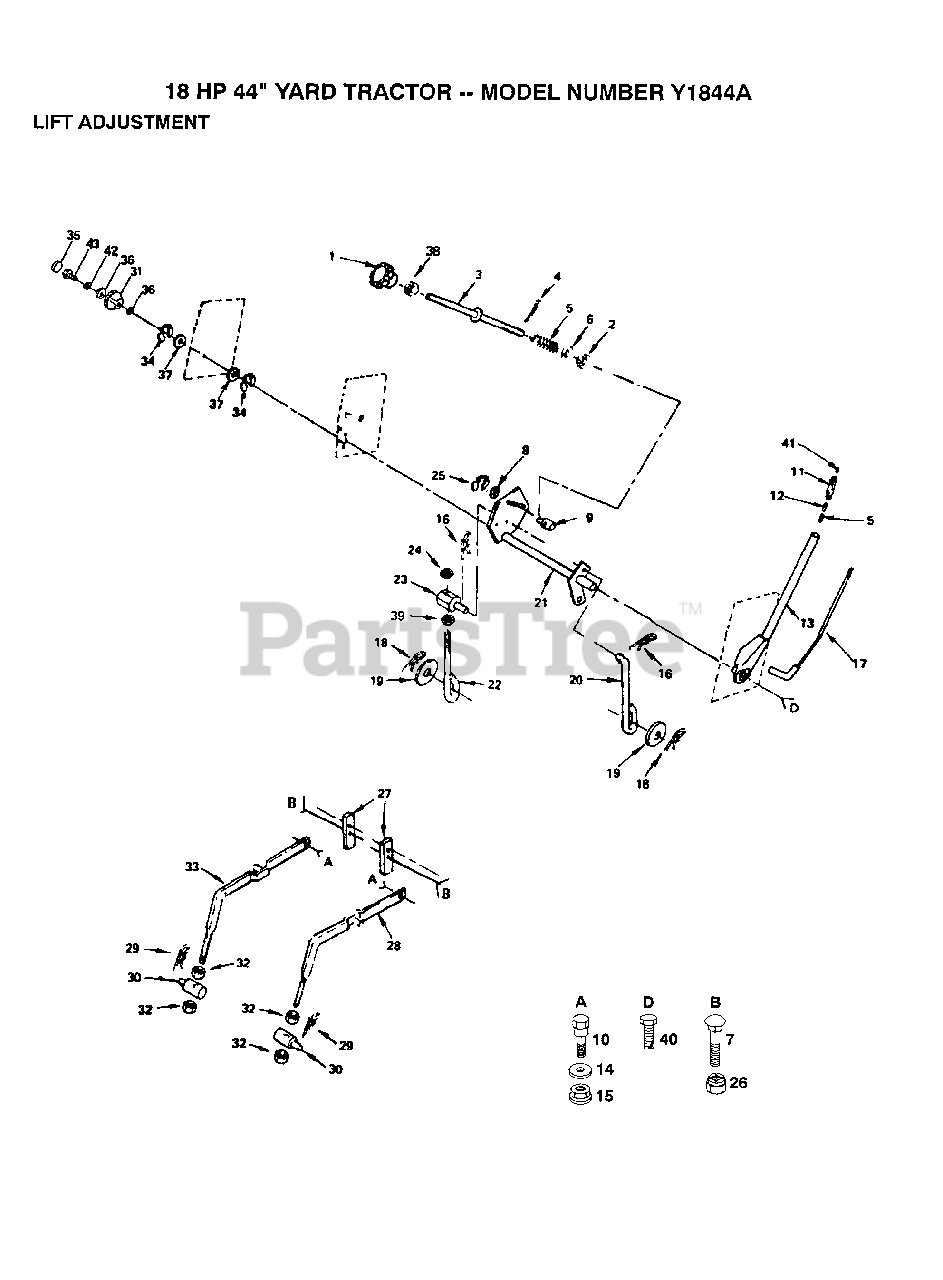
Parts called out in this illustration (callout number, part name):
2	NUT T
3	ROD LIFT LT
5	SPRING T
6	WASHER
8	WASHER
9	TRUNION LT
10	"BOLT, SHOULDER LT"
11	GRIP
14	WASHER T
15	NUT SPECIAL T
17	LEVER ROD LT
18	SPRING.RETAINER
20	LIFT LINK LT
22	PIVOT PIN T
25	KLIP RING
27	UPSTOP
28	RH SUSP ARM ASM
29	SPRING H
31	HEIGHT INDICATOR
32	NUT
33	LH SUSP ARM ASM
34	E-RING
35	"PLUG,HOLE"
36	WASHER
37	WASHER
38	NUT
39	NUT
40	"BOLT,HEX"
42	LOCKWASHER
